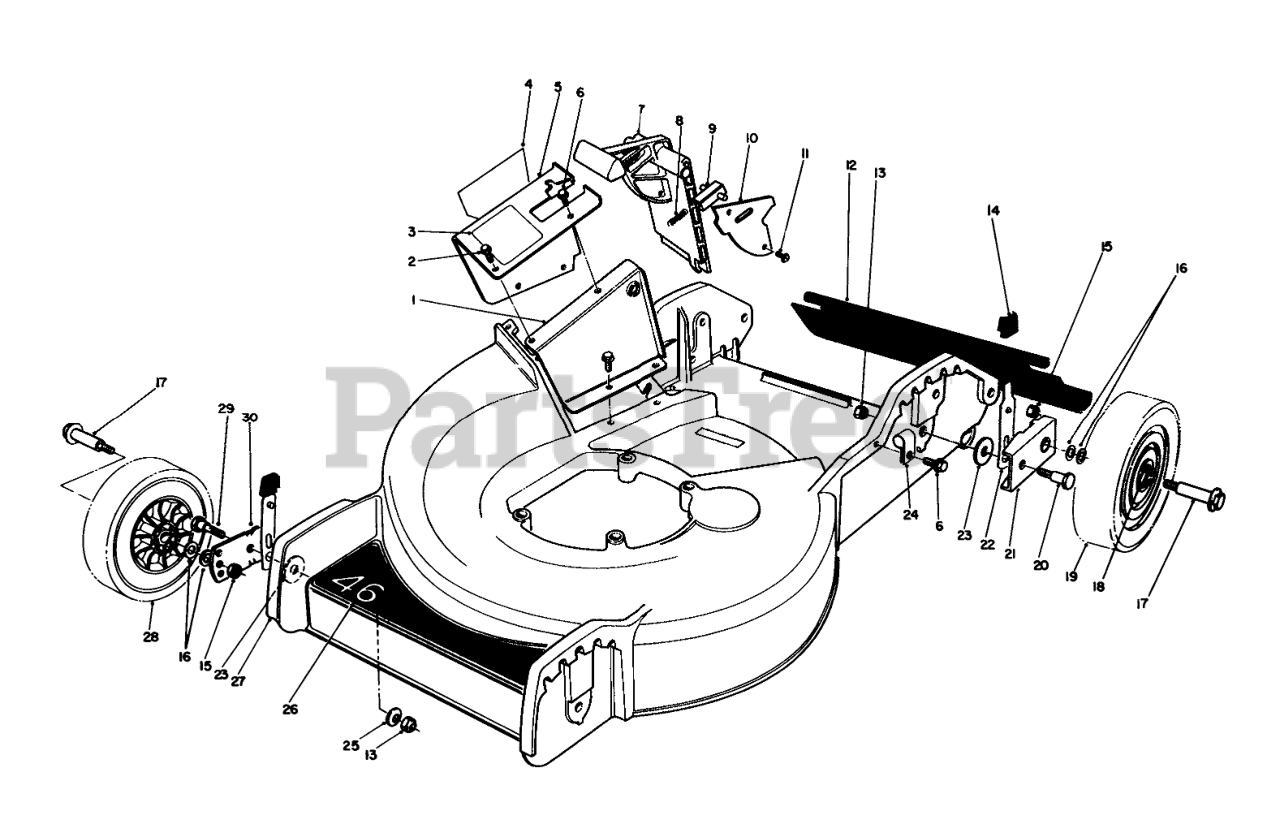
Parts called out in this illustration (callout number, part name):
1	Tunnel-Inner
2	SCREW
3	DECAL - DANGER
4	DECAL-DANGER
5	Tunnel-Outer (Incl. Ref. #3 & 4)
6	SCREW
7	Door Mulching
8	SPRING-COMPRESSION, LATCH
9	Door Latch
10	Cover Door
12	SHIELD - TRAILING
13	NUT-LOCK, NI
14	KNOB-ARM
15	Nut
16	WASHER
17	BOLT-WHEEL
18	BUSHING
19	Wheel & Tire Assembly (Incl. Ref. #18)
20	PIVOT SCREW
21	PIVOT ARM ASM
22	SPRING ARM ASM
23	PIVOT WASHER
24	CLAMP-R
25	WASHER-BELLEVILLE
26	DECAL - DECK
27	HSG & CARTON
28	Wheel & Tire Assembly (Incl. Ref. #18)
29	PIVOT SCREW
30	PIVOT ARM ASSY
